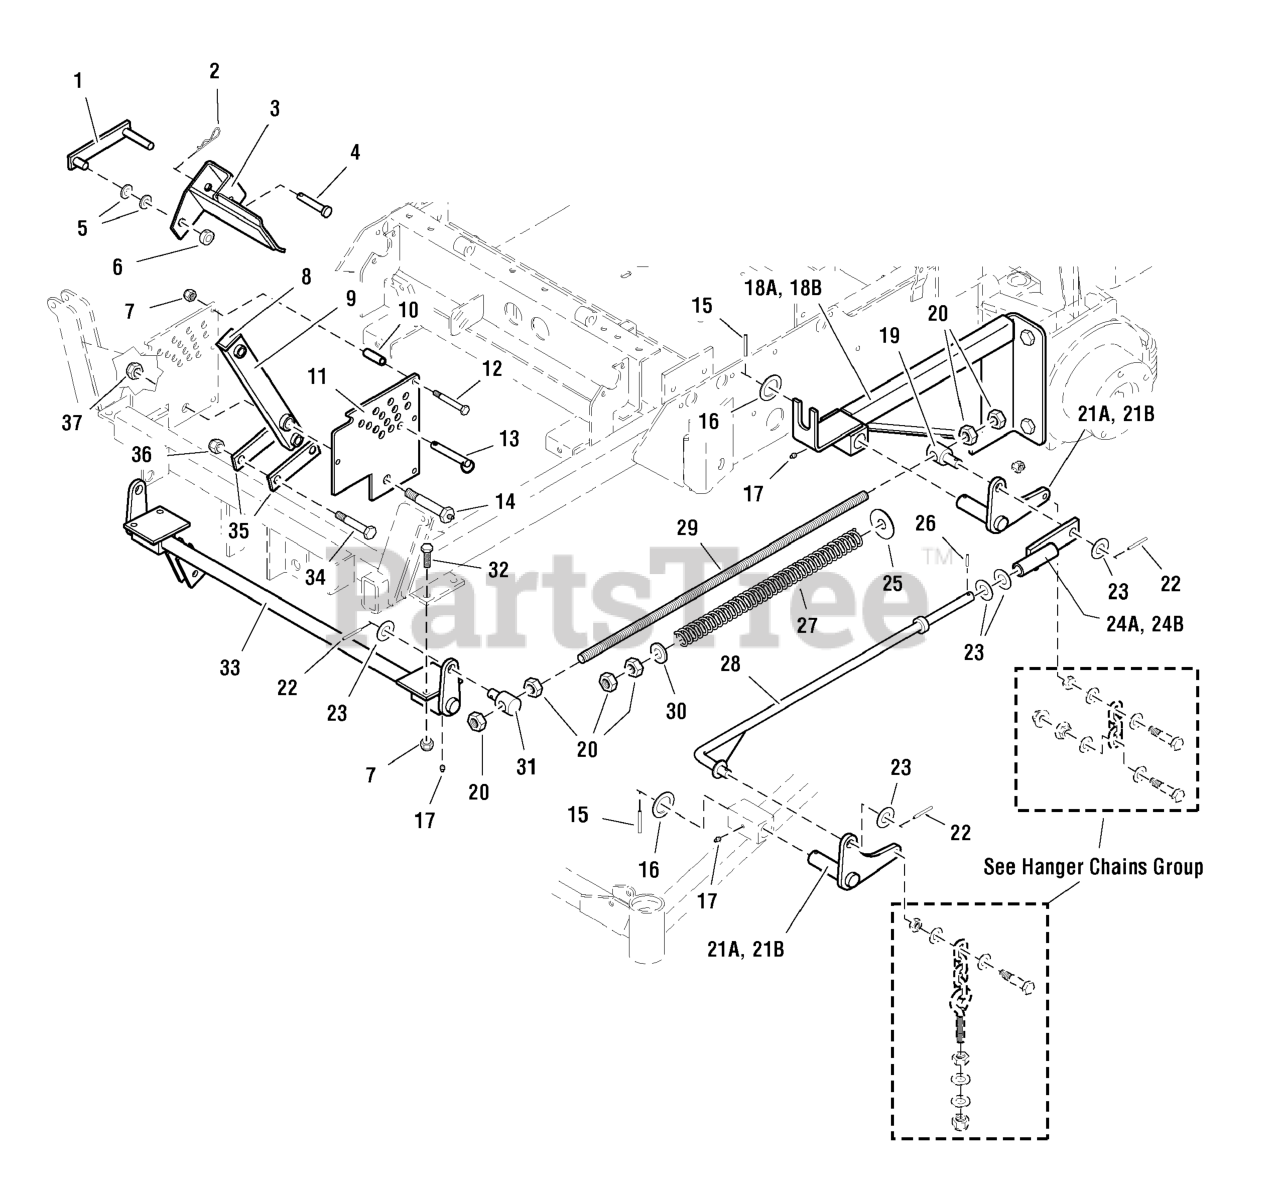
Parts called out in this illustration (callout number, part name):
1	DECK LIFT LOCK
2	HAIRPIN CLIP
3	WELD, DECK LIFT PEDAL
3	PEDAL SAFETY WALK
4	PIN, Clevis, 1/2 x 2-1/2
5	WASHER, 1/2 SAE
6	COLLAR, Split, 1/2
7	NUT, 3/8-16 HEX NYLON LOCK
9	ARM, Deck Lift Pivot
10	SPACER, .38 x .50 x 1.56
11	DECK HEIGHT PLATE
11	DECAL, Deck Height
12	BOLT, 3/8-16 X 2-3/4" GD5 CZ
13	PIN, 1/2 x 3-1/2 w/ Lanyard
14	LIFT PIVOT BOLT
15	PIN, Roll, 3/16 x 1-1/2
17	GREASE FITTING
18A	REAR DECK LIFT FRAME - LH
19	SPRING ROD PIVOT
20	NUT, 5/8-11 Hex
21A	DECK LIFT PIVOT - LH
22	PIN, Spring, 3/16 x 1-1/4
23	WASHER, 5/8" SAE
24A	DECK LIFT LINK - LH
25	WASHER, 5/8" USS
26	PIN, Roll, 3/16 x 3/4
27	SPRING, Deck Lift
28	DECK LIFT ROD
29	SPRING ROD
30	SPACER, .63 x 1.06 x .23
31	SPRING ROD PIVOT
32	BOLT, 3/8-16 X 1-1/4" GD5 CZ
33	DECK LIFT SHAFT & MOUNT ASSEMBLY
34	BOLT, 1/2-20 x 3
35	DECK LIFT LINK
36	NUT, Hex, Nylon Lock, 1/2-20
37	NUT, 5/8-11 Hex Jam Nylon Lock
